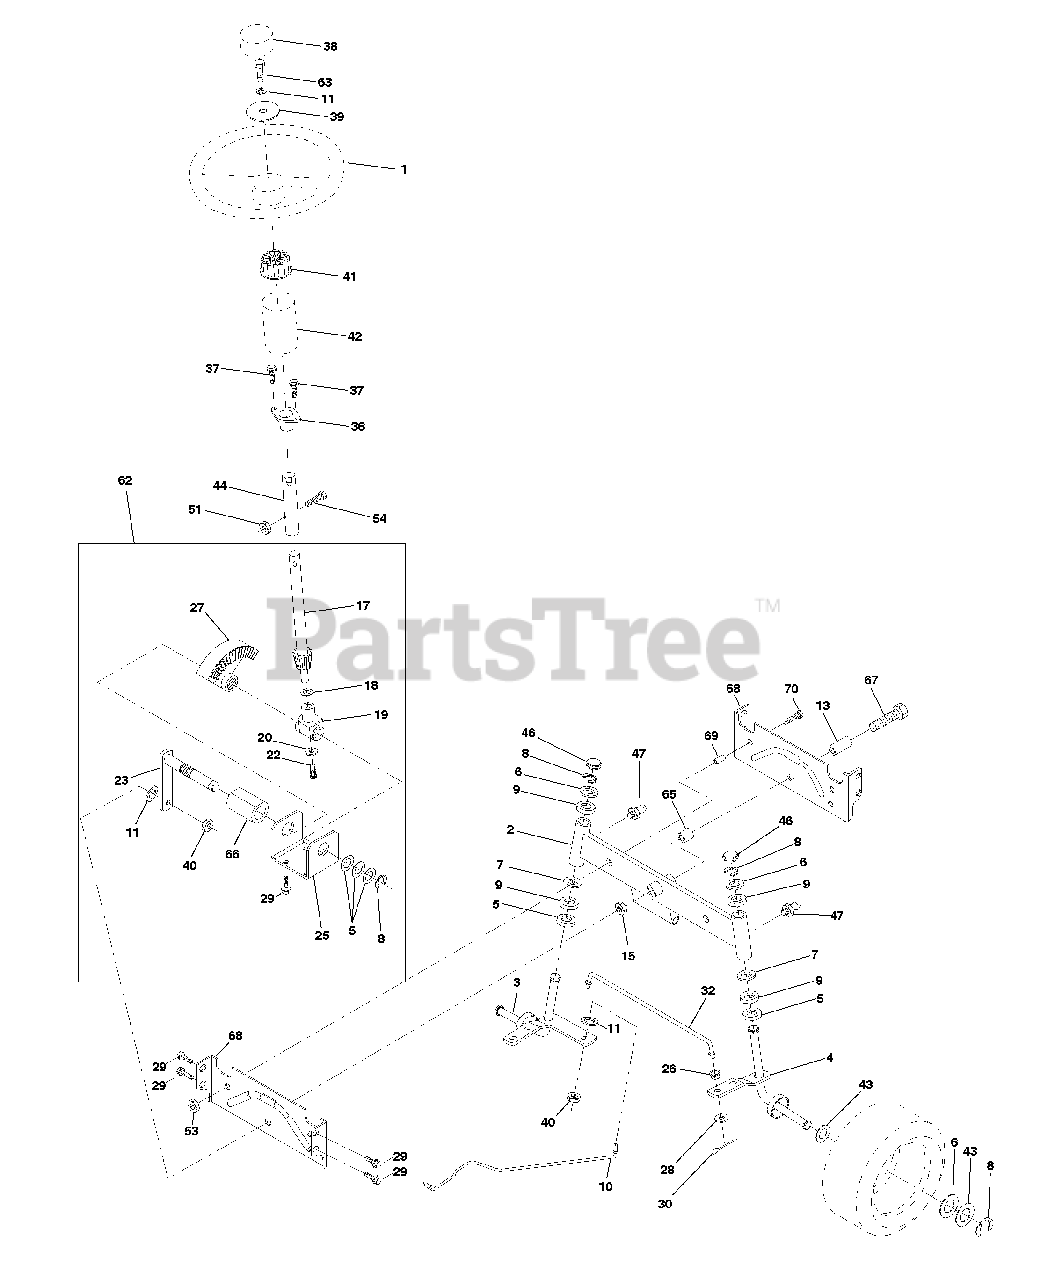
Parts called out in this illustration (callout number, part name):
1	Wheel Steering
2	Axle Asm STMP Dropped STL
3	Spindle Asm LH
4	Spindle Asm RH
5	Bearing Race Thrust Harden
6	Washer 25/32 X 1-5/8 X 16 Ga
7	Washer 27/32 X 1-1/4 X 16 Ga
8	Ring Klip #t5304-75
9	Bearing Col Strg Blk
10	Link Drag Extended Stamp
11	Washer Lock Hvy Hlcl Spr 3/8
13	Bearing Axle STLT/GT
15	Nut Lock Flange 5/8-11 Unc
17	Shaft Asm Strg
18	Washer Thrust 515 x 750 x 033
19	Support Shaft
20	Washer Shim 1/4 X 5/8 X 062
22	Screw Hex Socket 1/4-20 x 5/8
23	Shaft Asm Pittman
25	Bracket Steering
26	Bushing Link Drag Blk LR
27	Gear Sector
28	Washer 13/32 X 7/8 X 16 Ga
29	Screw Thdrol 3/8-16 x 3/4 Ty-tt
30	Pin Cotter 1/8 X 3/4 Cad
32	Rod Tie Wire Form 19 75 Mech
36	Bushing Strg
38	Insert Cap Strg Wh Au
39	Washer 13/32 X 2-3/8 X 8 Ga
40	Lock nut
41	Adaptor Wheel Strg
42	Boot Steering Shaft
43	Washer 25/32 X 1 1/4 X 16 Ga
44	Extension Steering Shaft LR/LT
46	Cap Spindle Fr Top Blk
47	Fitting Grease
51	Nut Lock Hex w/Ins 5/16-18
53	Nut Crownlock 3/8-16unc
54	Bolt Fin Hex 5/16-18 Unc x 1-1/4
62	Kit, Steering Assembly Svc
63	Bolt Fin Hex 3/8-16unc x 1 Gr. 5
65	Spacer Axle
66	Bearing Arm Pittman
67	Bolt, Fin Hex 5/8-11 UNC x 2-3/4
68	Axle, Brace
69	Spacer Brace Axle
70	Bolt Fin Hex 3/8-16unc x 2-1/4
